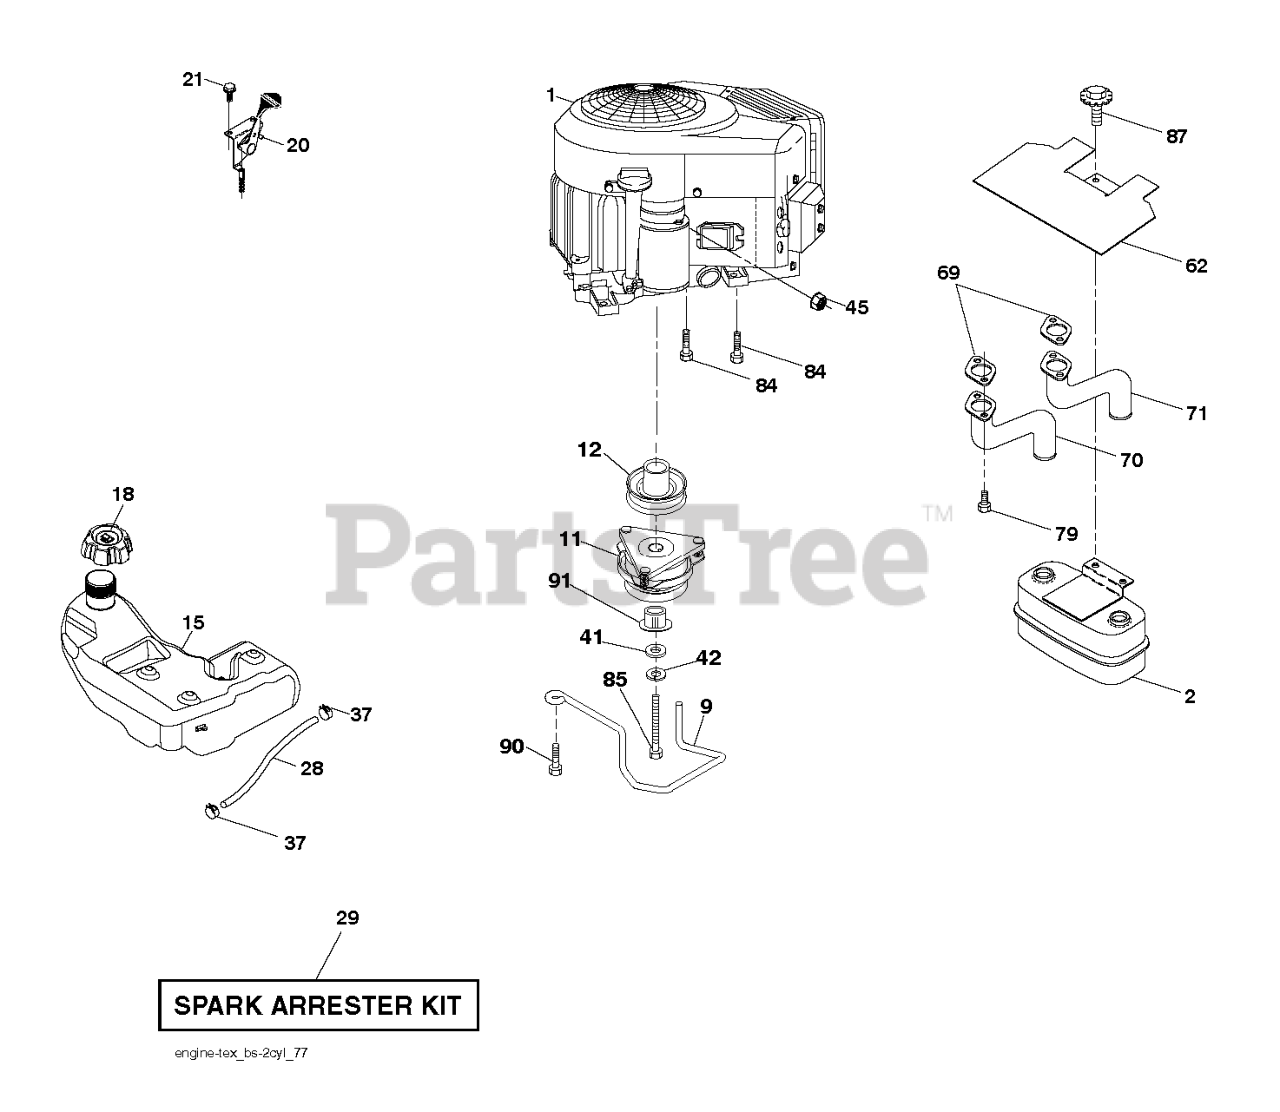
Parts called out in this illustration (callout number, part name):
2	MUFFLER.ASM.TWN.EXTNDED.DFLCTR
9	KEEPER.BELT.ENGINE.4.2
11	CLUTCH.ELECTRIC.LT.48"*
12	PULLEY.ENGINE.TUFFTORQ
15	RP_TANK.ASSY.3.GAL.EPA
18	CAP.ASM.FL.RITCH.3"E10.SYM.498
20	CONTROL.TH/CK.COBRA.B&S.TWN.BK
21	SCREW.#10 X 0.750.BOS
28	LINE.FUEL.64"REAR.EMIS
29	KIT.SPARK ARRESTOR 794945 B&S
37	HOSE CLAMP
42	LOCKWASHER
45	NUT
62	SHIELD.HEAT.MUFFLER
69	GASKET.MUFFLER
70	RP.EXHAUST.TUBE.LH.BS/TWIN
71	EXHAUST.TUBE.RH.BS/TWIN
79	SCREW.SOCKET.HEAD.5/16-18
84	SCREW.3/8-16
85	BOLT HEX 7/16-20X4-1/4"
87	BOLT 5/1618UNC X 3/4 W/ SEMS
90	SCREW 3/8-16X1
91	BUSHING.1.375OD
